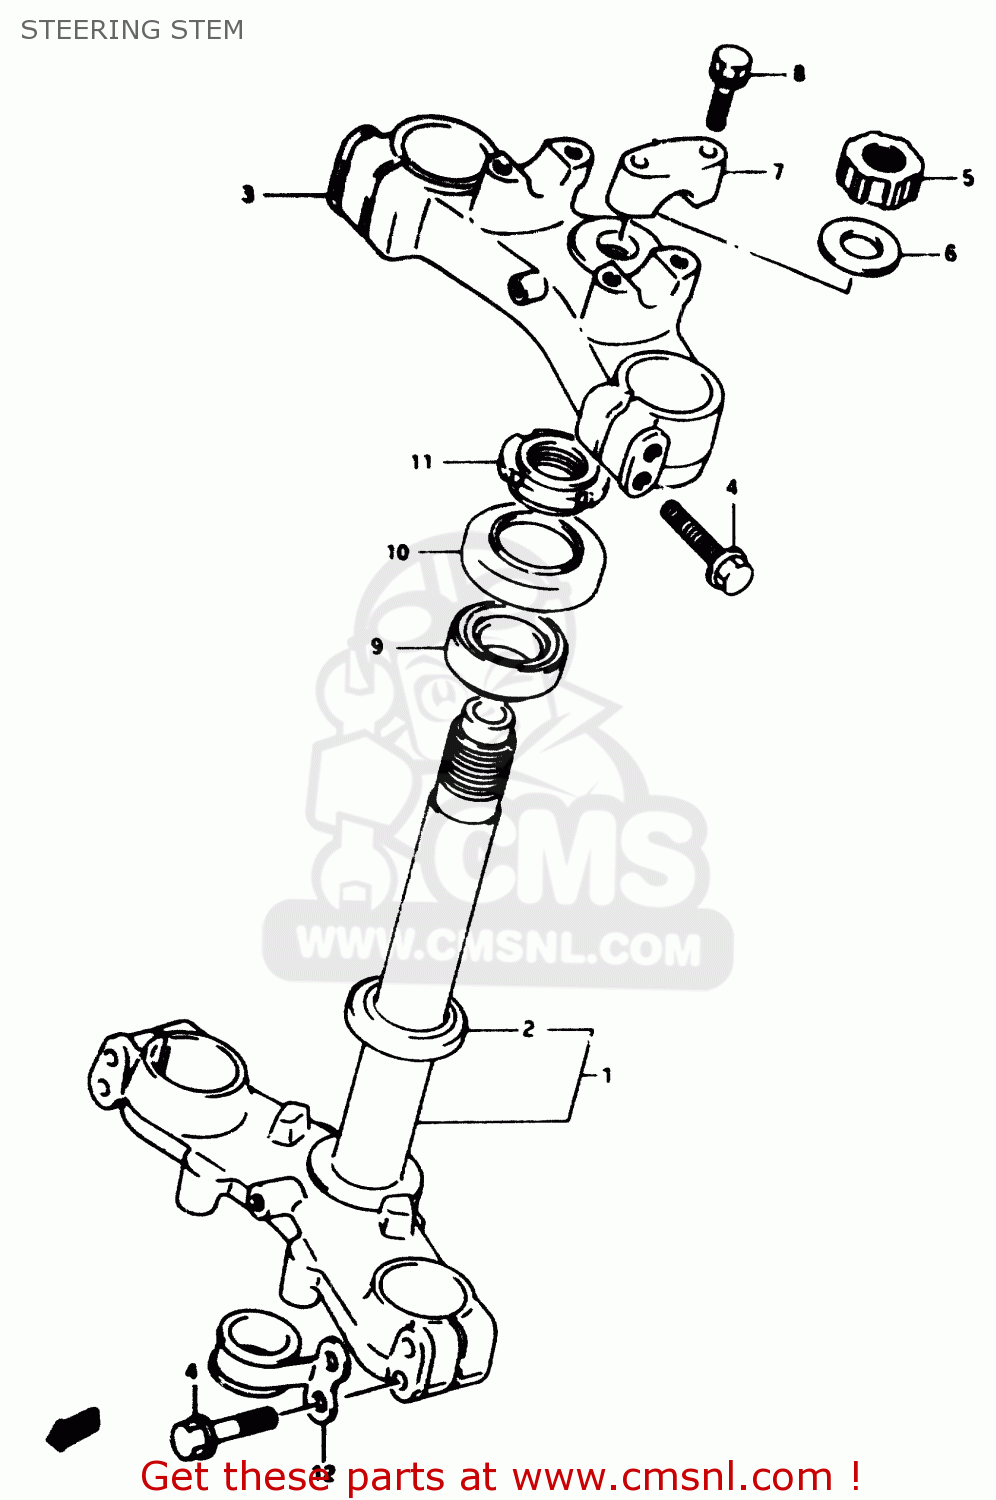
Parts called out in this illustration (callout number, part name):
1	STEM,STEERING
2	BEARING(26X47X15)
3	HEAD,STEERING STEM
4	BOLT
5	NUT
6	WASHER
7	HOLDER,HANDLEBAR
8	BOLT
9	TAPER,ROLLER BEARING
10	SEAL,STEERING UPR DUST
11	NUT,STEERING
12	CLIP
